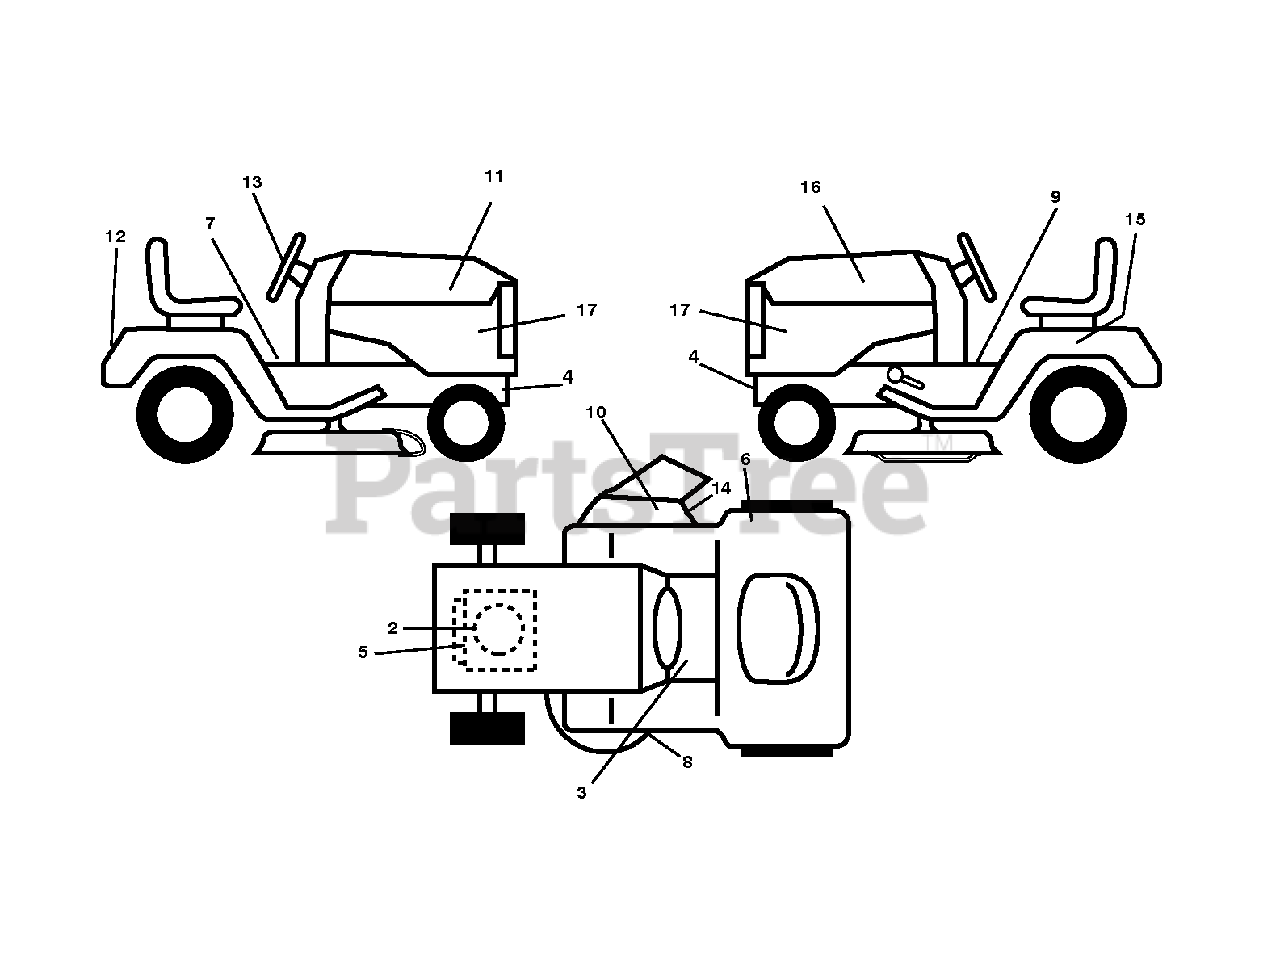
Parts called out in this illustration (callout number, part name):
6	Decal, 100 DB/CE
8	DECAL.V-BELT.SCHEMATIC.36/38/9
9	DECAL PARK BRAKE
10	DECAL.INTERNATIONL.CUTFINGER
14	DECAL, DEFLECT WARNING
15	DECAL BTRY SYMBOLS
